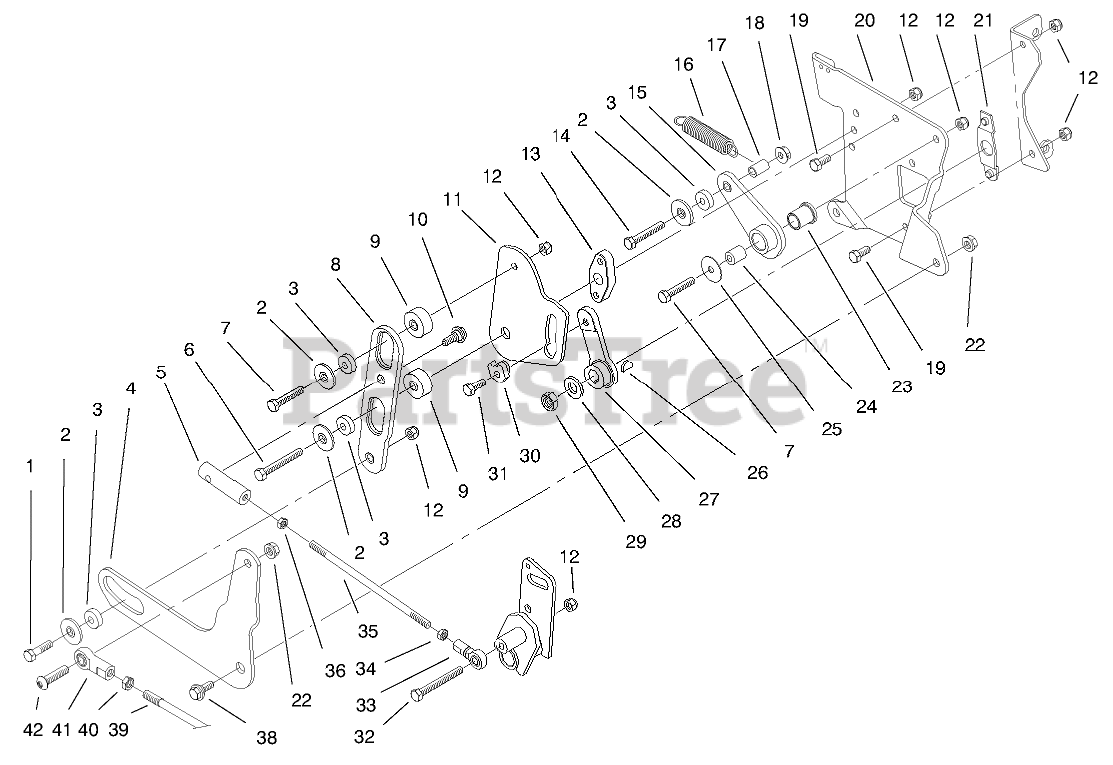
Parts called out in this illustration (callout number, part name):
1	SCREW-HH
2	RETAINER-BEARING
3	BEARING-BALL
4	SLIDER-LIFT
5	END-ROD, RH
6	SCREW-HH
7	SCREW-HH
8	SLIDER-CONTROL, SPEED
9	STANDOFF-CAM PLATE
10	BOLT-SHOULDER
11	PLATE-CAM
12	NUT-LOCK, NI
13	STANDOFF-SLIDER
14	SCREW-HH
15	ARM-RETURN TO NEUTRAL
16	SPRING-IDLER
17	STANDOFF-SPRING
19	SCREW-HH
20	Plate-Control
21	LOCATOR-CONTROL PLATE
23	BUSHING-FLANGED
24	SPACER
25	WASHER-FLAT
26	KEY-WOODRUFF
27	ARM-CONTROL, SPEED
28	WASHER-FLAT
29	NUT-LOCK, NI
31	SCREW-THREAD LOCKING
32	SCREW-HH
33	END-ROD, RH
34	NUT-JAM
35	ROD-SLIDER TO PIVOT
36	NUT-JAM
38	BOLT-SHOULDER
39	ROD-LIFT
40	NUT-HJ
41	END-ROD, FEMALE
42	SCREW-HSBH
